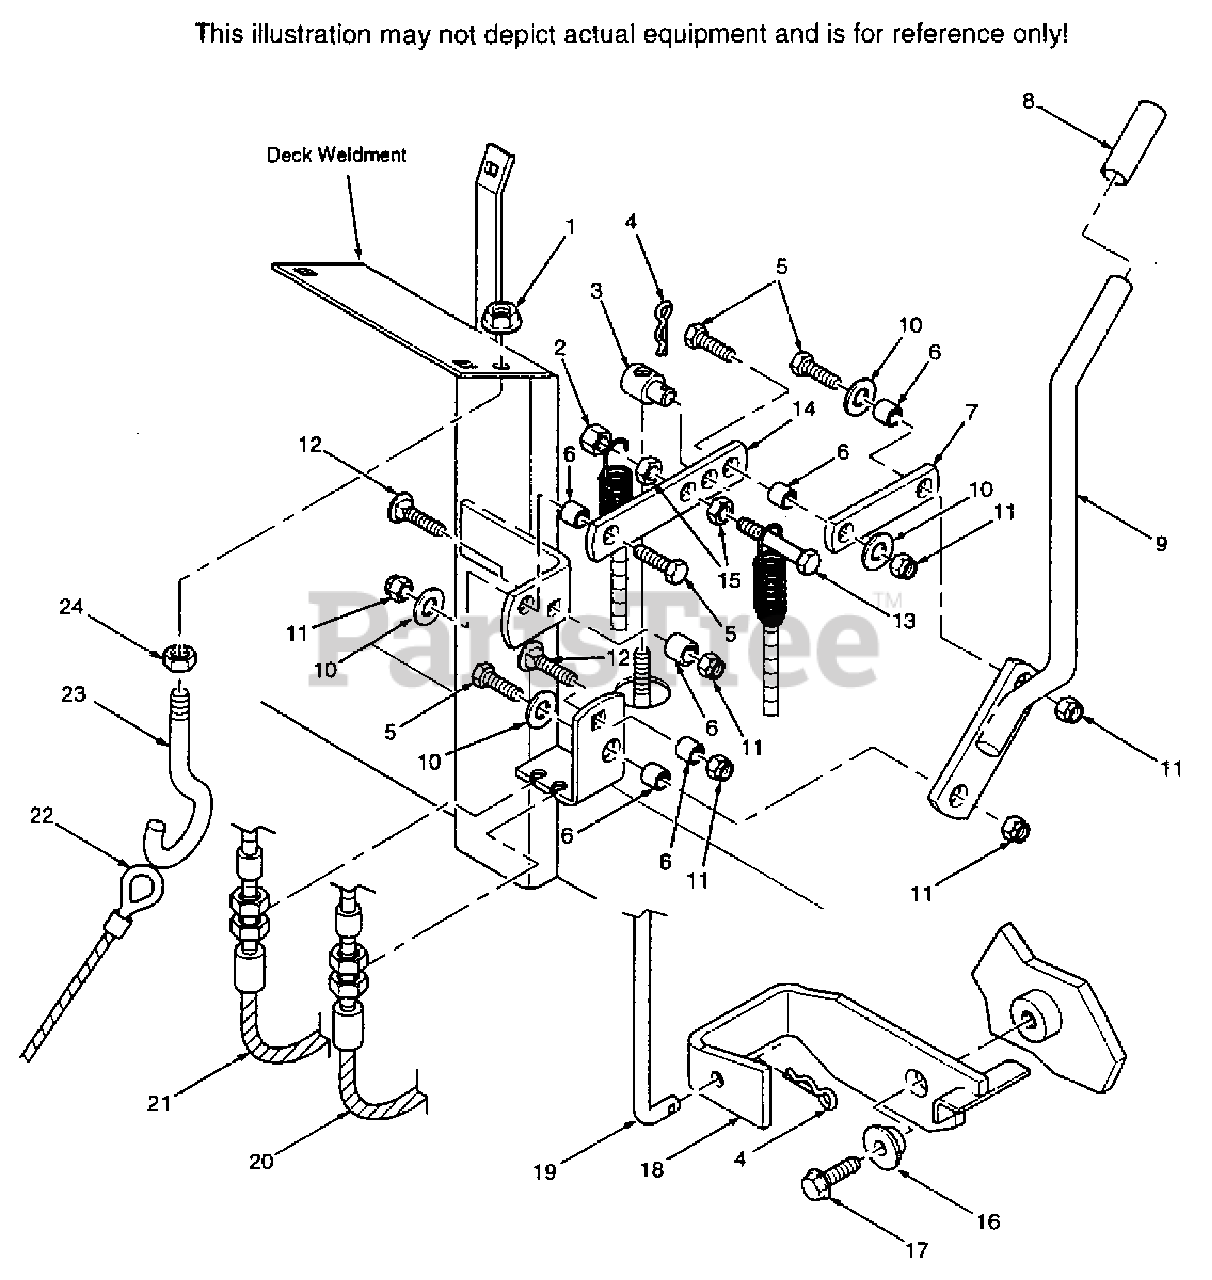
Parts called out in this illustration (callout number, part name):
1	SERR. FL. HH NUT, 3/8-16
3	SWIVEL
4	COTTER PIN
6	SLEEVE, HYDRO LINKAGE
7	LINK, CAM
8	GRIP, PARKING BRAKE
9	HANDLE, PARKING BRAKE
10	FLAT WASHER, 3/8 X 15/16 X 12 GA.
14	LEVER, BRAKE
16	WASHER, NEUTRAL LOCK
17	SERR. FL. HH CPSCR, 3/8-16 X 1
18	BRACKET, NEUTRAL LOCK
19	ROD, NEUTRAL LOCK
20	CABLE ASSEMBLY, PARKING BRAKE R.H.
21	CABLE ASSEMBLY, PARKING BRAKE L.H.
22	CABLE WINCH
23	EYE BOLT, 3/8-16 R.H.
